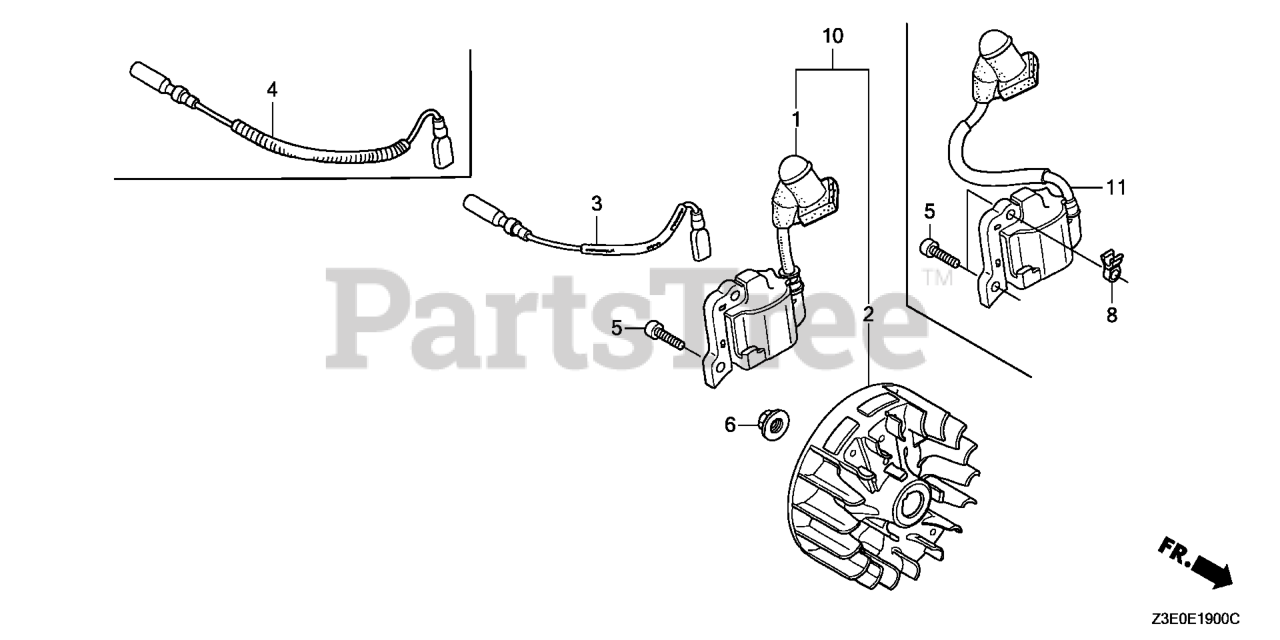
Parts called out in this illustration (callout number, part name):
1	COIL ASSY., IGNITION
2	FLYWHEEL
3	WIRE, STOP SWITCH
5	BOLT, SOCKET (4X14)
6	NUT, FLANGE (7MM)
10	IGNITION COIL & FLYWHEEL KIT
